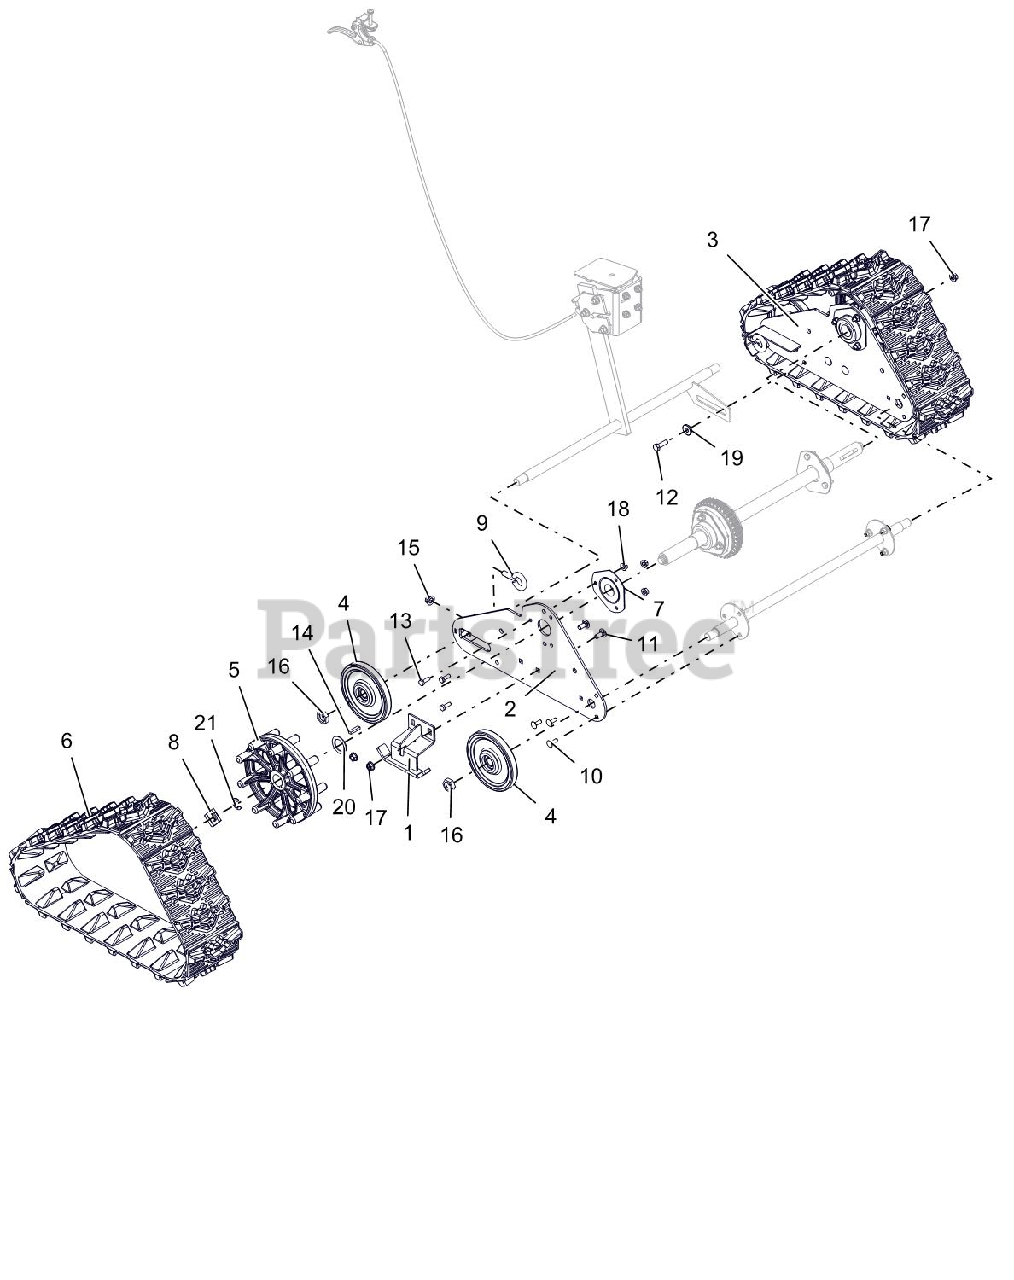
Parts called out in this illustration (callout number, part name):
1	RUNNER, GUIDE-TRACK
2	SIDE PLATE, RH-TRACK
3	SIDE PLATE, LH-TRACK
4	WHEEL, BOGIE - SINGLE BEARING
5	WHEEL, MACHINED DRIVE
6	TRACK, RUBBER
7	BRG-FLG 1.003/1.000 3 BOLT
8	CLIP, SNAP .625 DIA
9	BLT-EYE .375-16X.880 YWZC
10	@BLT-RDHDSQNK .25-20X.75 G5YZ
11	@BLT-RDHDSQNK .31-18X.75 G5YZ
12	@BLT-HEX .25-20X.75 GR5 YWZC
13	@BLT-HEX .25-20X.75 GR5 YWZC
14	KEY-RECT .25X.188X1.00
15	@NUT-LK-CTR-FLG .25-20 YWZC
16	@NUT-LK-NYL .625-18 YWZC
17	@NUT-LK-TOP-FLG .31-18 YWZC
18	@NUT-LK-TOP-FLG .25-20 YWZC
19	BSHG-FLG .325X.499X.3X.875
20	WSHR-FL-STL 1.010X1.505X.062YZ
21	RG-RTNG-EXT .625X.042
